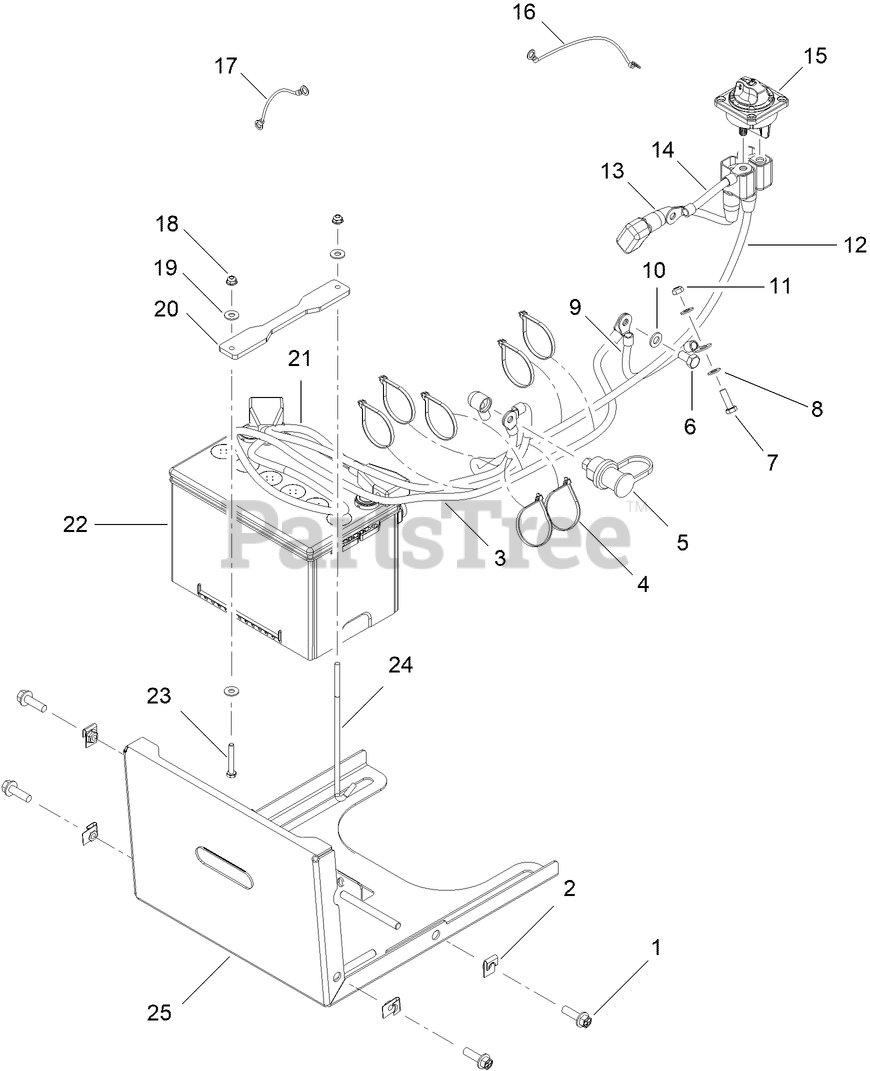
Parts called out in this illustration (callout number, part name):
1	SCREW-HHF
2	NUT-SPRING
3	BATT CABLE NEG. (1GA X 46 INCHES, BLK)
4	CABLE TIE (1/16" TO 4")
5	BATTERY JUMPER TERMINAL (RED)
6	SCREW-HH
7	SCREW-HH
8	WASHER-PLAIN
9	GROUND STRAP
10	WASHER-FLAT
11	NUT-HEX
12	JUMP START CABLE (1GA X 38 INCHES, RED)
13	STARTER CABLE (1GA X 8 INCHES, RED)
14	TRIFUSE CABLE (1GA X 4.25 INCHES, RED)
15	SQUARE DISCONNECT SWITCH (300A)
16	GROUND BRAID - L ARM PANEL TO CRUISE
17	GROUND BRAID - L ARM PANEL TO CRUISE
18	NUT-HF
19	WASHER-FLAT
20	BATTERY HOLD DOWN
21	BATT CABLE POS. (1GA X 30 INCHES, RED)
22	BATTERY-775CCA, 12V AGM
23	SCREW-HH
24	J-HOOK
25	BATTERY TRAY - WELD
